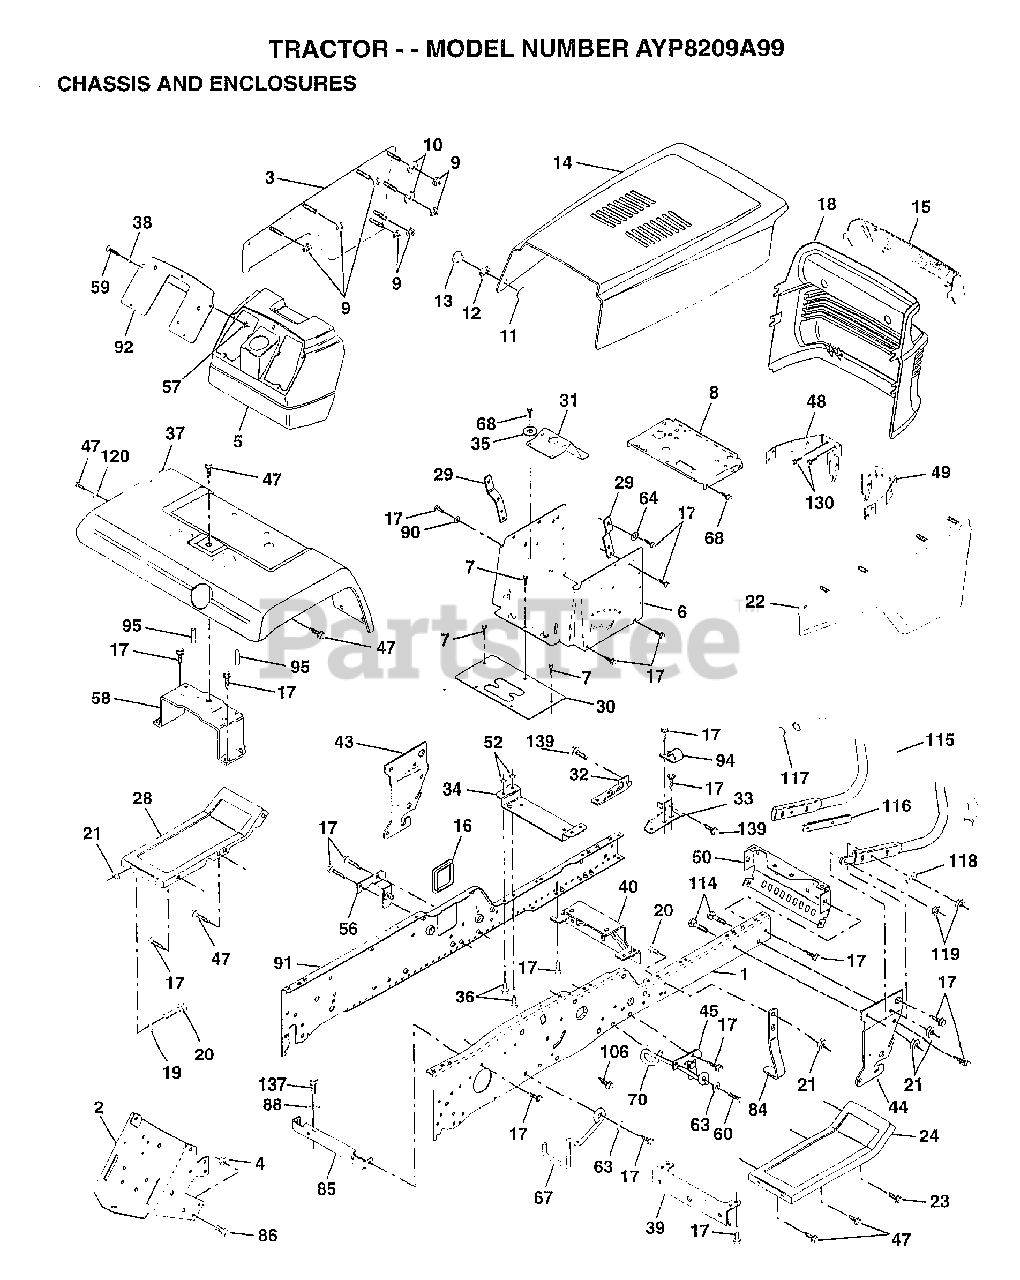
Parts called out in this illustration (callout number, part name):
1	"RAIL,FRAME RH"
2	DRAWBAR GT
3	PANEL.ASM.SIDE.LH
4	NUT GTV
5	DASH.PLASTIC.BLK
6	DASH LOWER
7	SCREW
8	SUPPORT.DASH.BTRY
9	PAL NUT LT
10	WASHER
11	RIVET.RATCHET.MAL
12	WASHER.NYLON
13	RIVET.RATCH.FEMAL
15	LENS.YT.GT.SEARS
16	COVER ACCESS
17	SCREW
19	WASHER
20	BOLT
22	PANEL.ASM.SIDE.RH
23	SCREW GTV
24	FOOTREST.RH.LT/GT
28	FOOTREST.LT.LT/GT
29	BRACKET.SUPT.DASH
30	SADDLE.SCR.6SP
31	BRKT SUPT 1-PC VG
32	BKRT.PIVOT.CHASSIS.LH
33	BKRT.PIVOT.CHASSIS.RH
34	BRACKET.ENG.SUPT.
35	WASHER
36	BOLT
37	"FENDER,RH"
38	WASHER PM
39	BRACKET.AXLE.FRT.
40	"BRKT SUPPORT,AXLE"
43	BRACKET.SUS.FT.LH
44	BRACKET.SUS.FT.RH
45	BRACKET.SUSP.RH.
47	SCREW LT
48	BRKT ASM PIVOT LH
49	BRKT ASM PIVOT RH
50	"BRKT CHASSIS,FRNT"
56	BRACKET.SUSP.LH.
57	NUT HXKEP 1/4X20
58	BRKT.ASM.FENDER
59	SCREW
60	SCREW
63	WASHER
64	WASHER.SERRATED.
67	"GUIDE BELT, T/A"
68	SCREW LT
70	GUIDE.BELT.MID.SP
84	STOP.OVER.CENTER
85	BRACKET.SUPT.TRAN
86	BOLT
88	LOCKWASHER
90	LOCKWASHER
91	"RAIL FRAME,LH"
92	PLATE.DASH.SKSCR.SRS
95	NUT-PUSH YT
114	BOLT.3/8-14X1.25
115	BUMPER.ASM
116	BRACKET.EXT.BUMP.
117	PLUG.PLASTIC
118	WASHER
120	WASHER HYT
130	"SCREW,HWHD.HI-LO#13-16X3/4"
137	BOLT.FIN.HEX.
139	BOLT.SHOULDER.5/16-18
